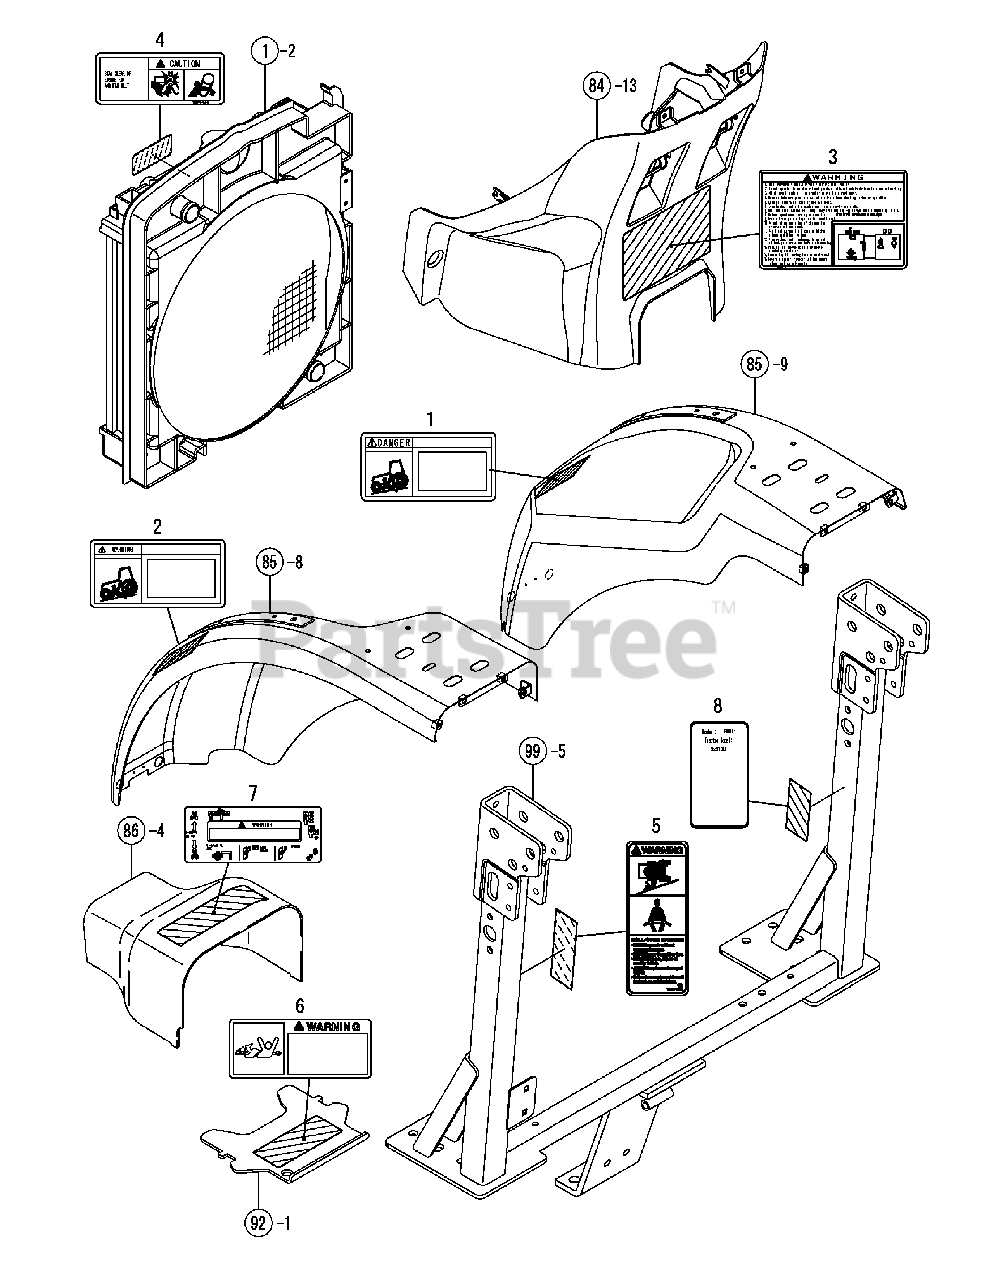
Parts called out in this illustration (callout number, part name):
1	Label,Danger,Start
2	Label,Warnibg,Stop
3	Label, Warining
4	Label,Warning,Fan
5	Label,Rops Warning
6	Label, P.T.O.Warning
7	Label,Operation H
